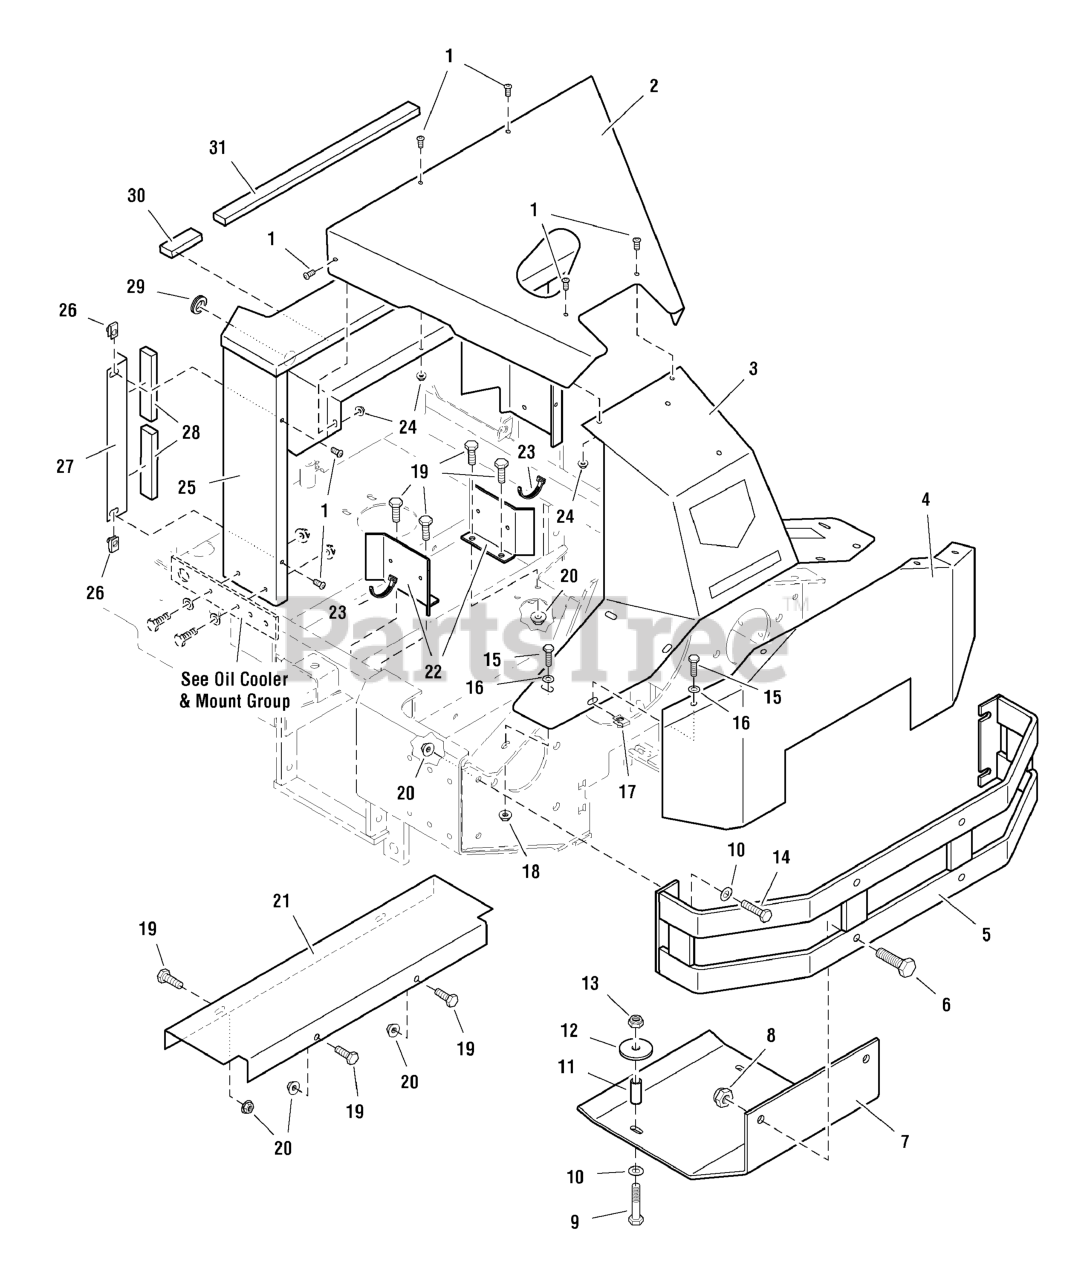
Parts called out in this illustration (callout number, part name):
1	SCREW, Allen Head, 1/4-20 x 1/2
3	REAR HOOD SUPPORT
4	REAR SHIELD
6	BOLT, 1/2-20 X 1-1/2, GD5 CZ
7	SKID SHIELD
8	NUT, Hex, Nylon Lock, 1/2-20
9	BOLT, 3/8-16 X 2-1/2" GD5 CZ
10	WASHER, 3/8 SAE
11	SPACER, .38 x .50 x 1.56
12	WASHER, 3/8 x 1-3/4
13	NUT, 3/8-16 HEX NYLON LOCK
14	BOLT, 3/8-16 X 1-1/4" GD5 CZ
15	BOLT, 5/16-18 X 1 GD5 YZ
16	WASHER, 5/16" SAE
17	BODY CLIP, 5/16-18-7GA MATERIAL
18	NUT, 5/16-18 HEX SERRATED FLANGE (SMALL)
19	BOLT, 3/8-16 X 1" GD5 CZ
20	NUT, 3/8-16 Hex Serrated Flange
21	DEBRIS SHIELD
22	SUPPORT PLATE
23	TIE WRAP, 11"
24	NUT, 1/4-20 HEX SERR. FLANGE
25	RADIATOR SHROUD
26	BODY CLIP, 1/4-20
27	RADIATOR SEAL ANGLE
28	FOAM SEAL, 7"
29	GROMMET, 1/2"
30	FOAM SEAL, 2"
31	FOAM SEAL, 16"
